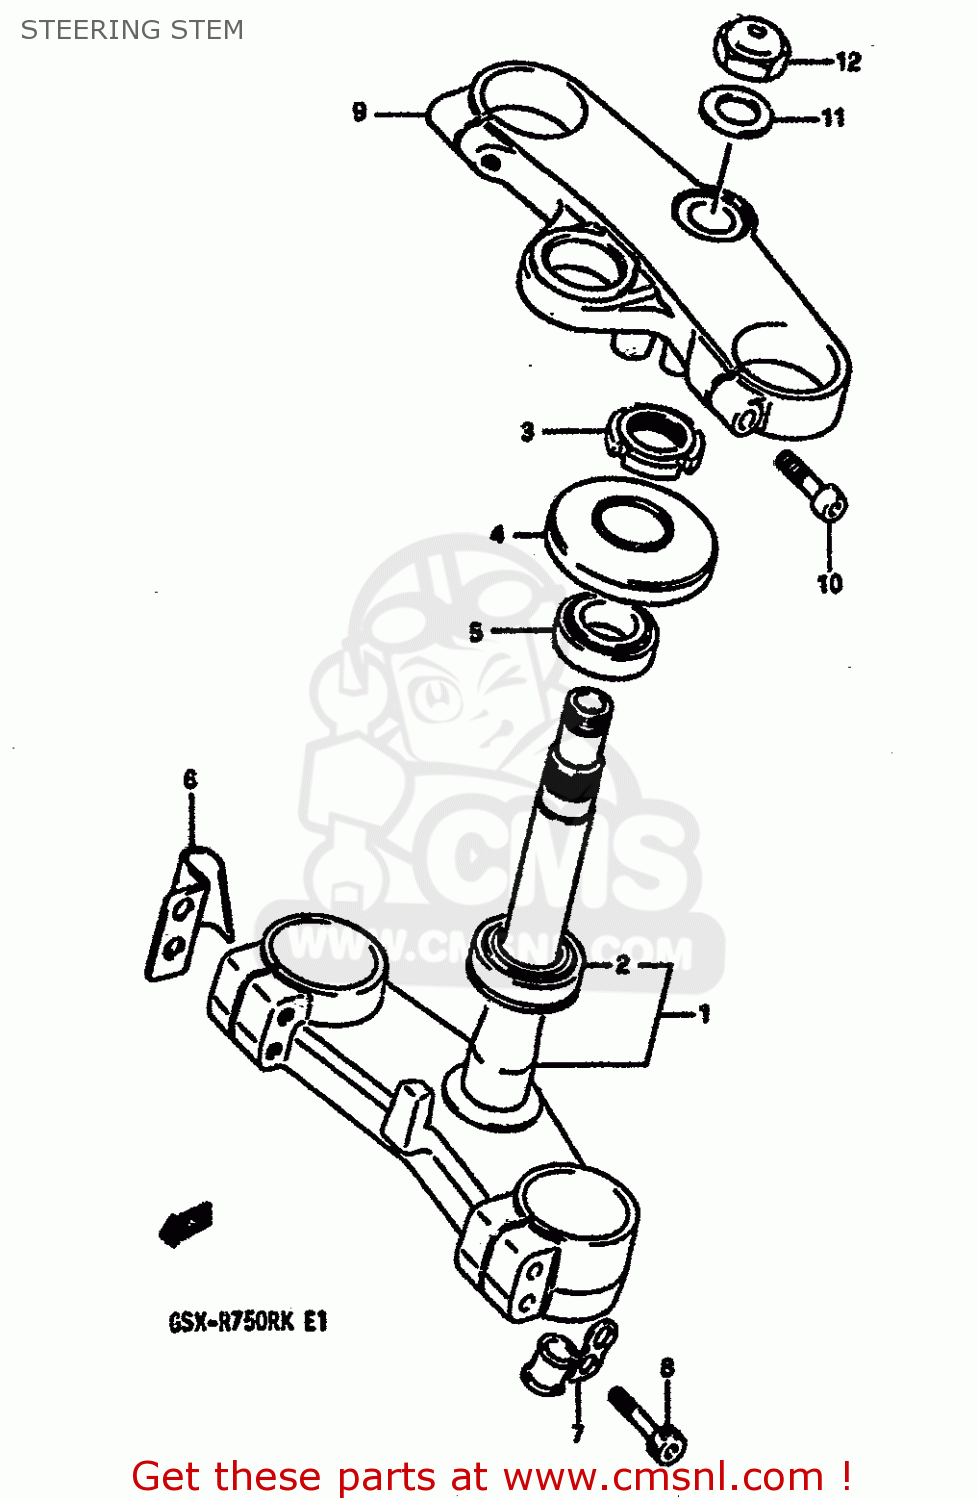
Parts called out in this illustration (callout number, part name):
1	STEM,STEERING
2	BEARING
3	NUT,STEERING STEM(25X44X10)
4	SEAL OIL
5	TAPER,ROLLER BEARING
6	CLAMP,CLUTCH CABLE
7	CLAMP,METER CABLE LH
8	BOLT 10X45
9	HEAD,STEERING STEM
10	BOLT
11	WASHER
12	NUT,STEM HEAD
